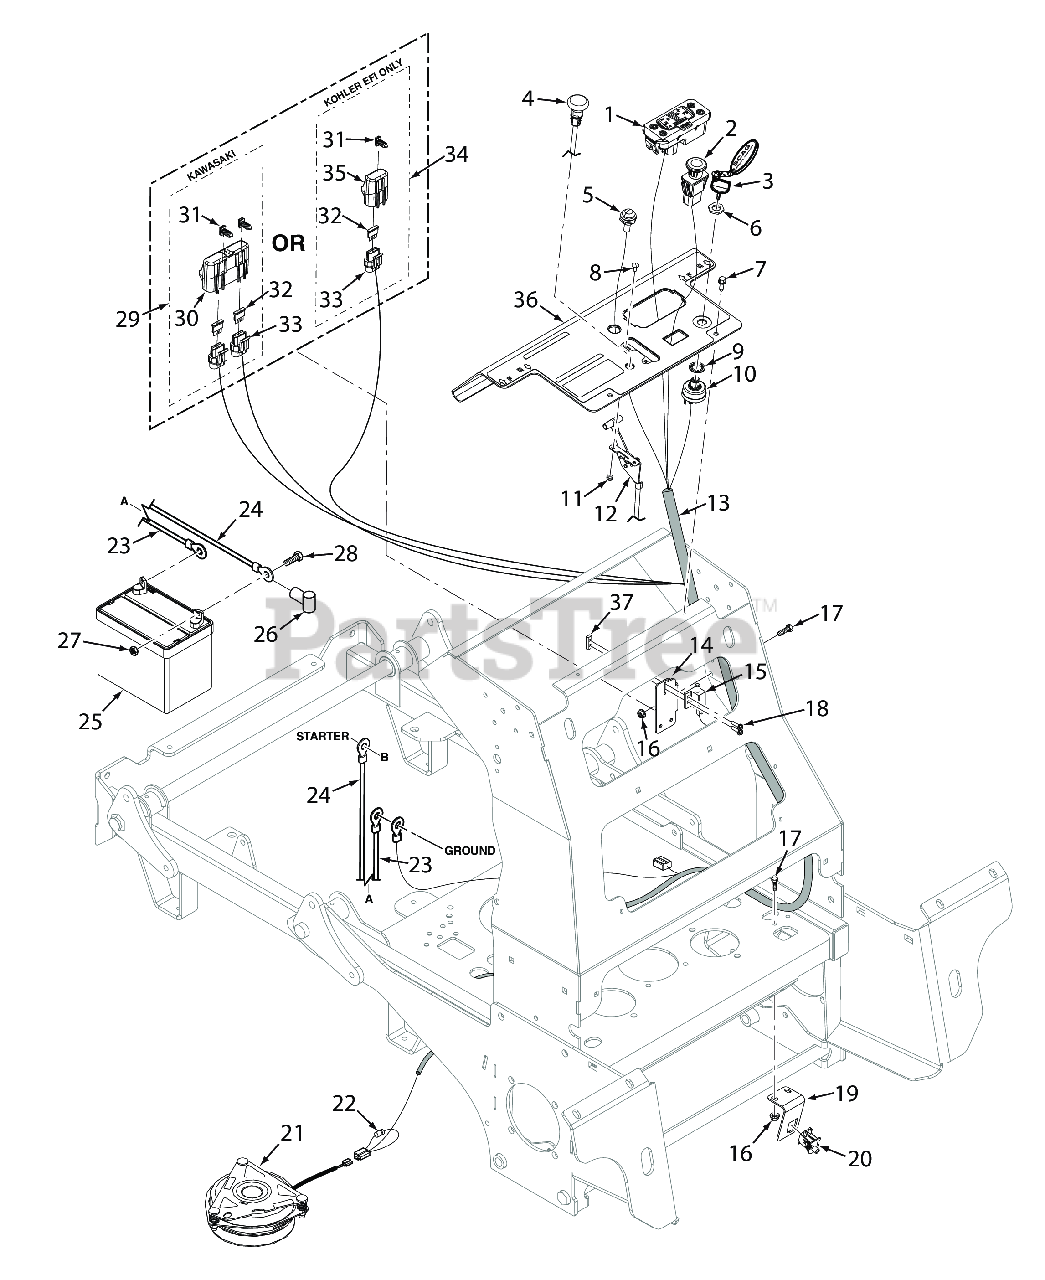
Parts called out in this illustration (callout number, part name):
1	Tiger Eye, Cluster Gauge
2	Switch, PTO - 10 Amp
3	Key, Assembly w/Fob
4	Choke Control (excludes EFI models)
5	Indicator Light, Glow Plugs (Includes Mounting Hardware)
6	Nut, 5/8-32 Special
7	Screw, Self-Tapping 1/4-20 x 3/4
8	Bolt, Carriage #10-24 x 1/2"
9	LOCK WASHER, 5/8" INTERNAL TOOTH
10	KEY SWITCH(INCLUDES MOUNTING HARDWARE)
11	Nut, Elastic Stop #10-24
12	Throttle Control, SVR
13	Wire Harness, SVRII
13	Wire Harness, SVRII-EFI
14	Bracket, Neutral Switch
15	Switch, Interlock, Park Brake Normally Open
16	NUT, 1/4-20 SERRATED FLANGE HEX HEAD
17	BOLT, HEX HEAD, 1/4-20 X 3/4 GR.5
18	Screw, Hex-Slotted Washer Head #10 32 x 3/4"
19	Switch Bracket, Operator Presence
20	SWITCH, NEUTRAL INTERLOCK
21	Clutch w/Tag GT2.5-FE02 (48 / 52)
21	Clutch w/Tag GT3.5--FE05 (61)
22	Diode, 600V 6 Amp
23	Battery Cable, 39" Black (26EFI) - Kohler
24	Battery Cable, 44" Red w/Braid (26EFI) - Kohler
25	Battery, 350 CCA (not available through Scag)
26	RUBBER BOOT
27	Nut, 1/4 - 20 Hex
28	BOLT, HEX HEAD, 1/4-20 X 3/4 GR.5
29	Double Fuse Assy.
30	Cover, Sealed Double
31	Clip, Fuse Holder
32	FUSE, 20 AMP BLADE TYPE AUTOMOTIVE
33	Fuse Holder Assembly
34	Single Fuse Assy., Excluding Fuse
35	Cover, Sealed Single
36	Control Panel w/Decal
37	Plate, Threaded
